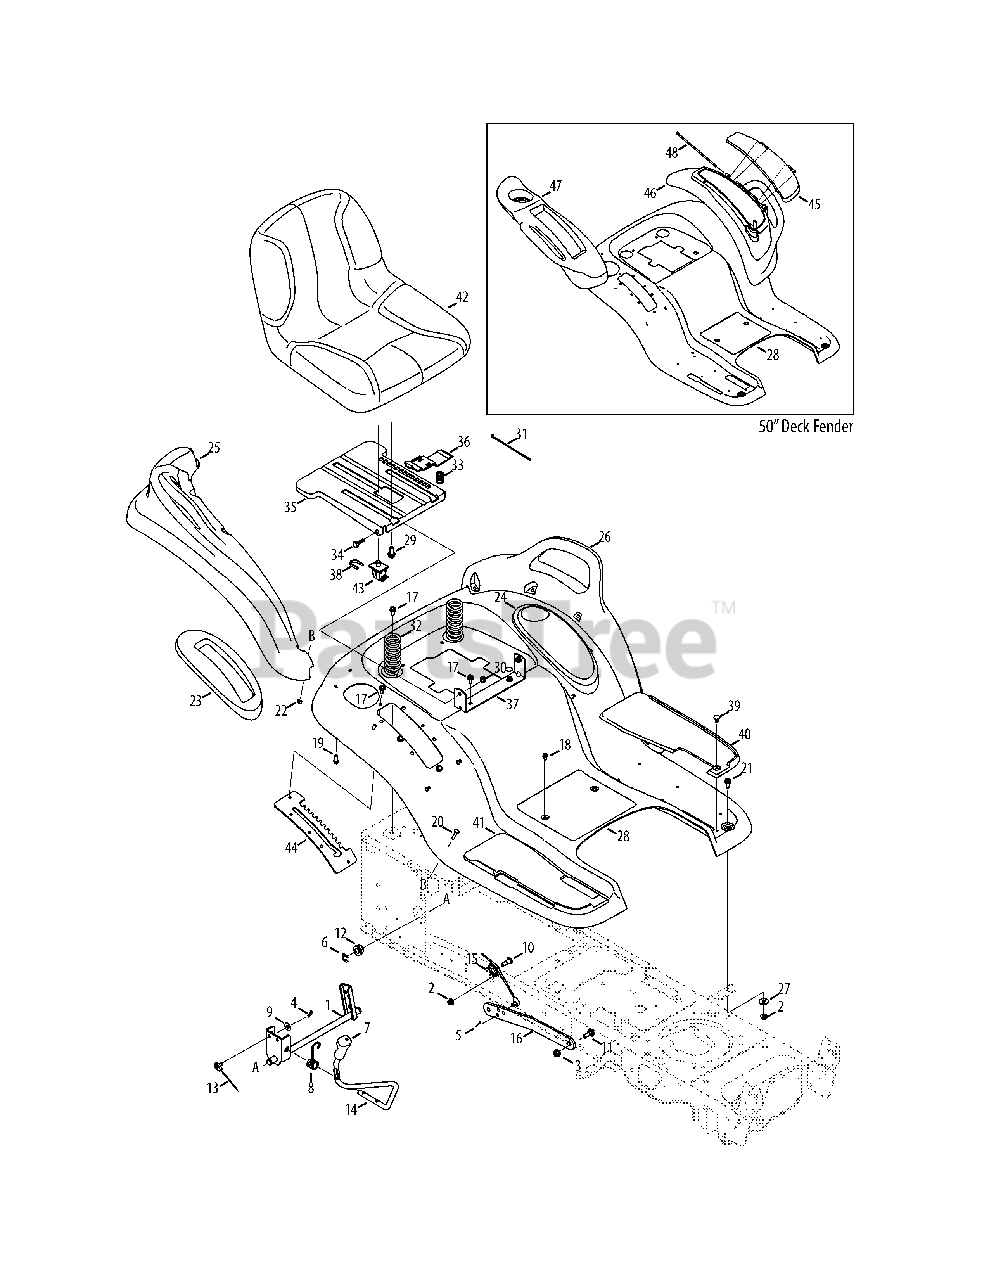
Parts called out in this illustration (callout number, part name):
1	Lift Shaft Assembly
2	Flangelock Nut, 5/16-18
3	Flangelock Nut, 3/8-16
4	Cotter Pin, .072 DIA. x 1.13 LG
5	Bow-Tie Cotter Pin
6	E-Ring, .625 DIA. SHAFT
7	Handle Grip
8	Torsion Spring
9	Spring Washer, .401 x .870 x .063
10	Shoulder Screw, .437 x .470:5/16-18
11	Shoulder Bolt, .500 x .270:3/8-16
12	Hex Flange Bearing
13	Lift Cable, 16.16 LG
14	Lift Handle
15	Pulley Roller Cable
17	Taptite Screw, Lock Washer, 5/16-18:.750
18	Taptite Screw, Lock Washer, 1/4-20
19	Hi-Lo Screw, Lock Washer, 1/4-15
20	Carriage Screw, 1/4-20:1.00
21	Taptite Screw, 5/16-18:.750
22	Sems Nut, 1/4-20
23	Lift Lever Cover
24	Cover with Cup Holder
25	RH Fender Flare
26	LH Fender Flare
27	Flat Washer, .344 x 1.00 x .063 HDN
29	Hex Head Flange, 3/8-16:.875
30	Flangelock Nut, 5/16-18
31	Cable Tie, 3/16 x .05 x 7.4
32	Compression Spring, 1.50 x 3.90 x .200
33	Compression Spring, .68 x 1.065 x .055
34	Shoulder Screw, .437 x .268:5/16-18
35	Seat Mounting Bracket
36	Seat Adjustment Lever
37	Seat Pivot Bracket
38	Switch Retainer Clip
39	Ratchet Clip
40	LH Foot Pad
41	RH Foot Pad
42	Seat
43	Seat Switch
44	Lift Bracket
45	Fender Cover Door
46	LH Fender Cover
47	RH Fender Cover
48	Door Pin
